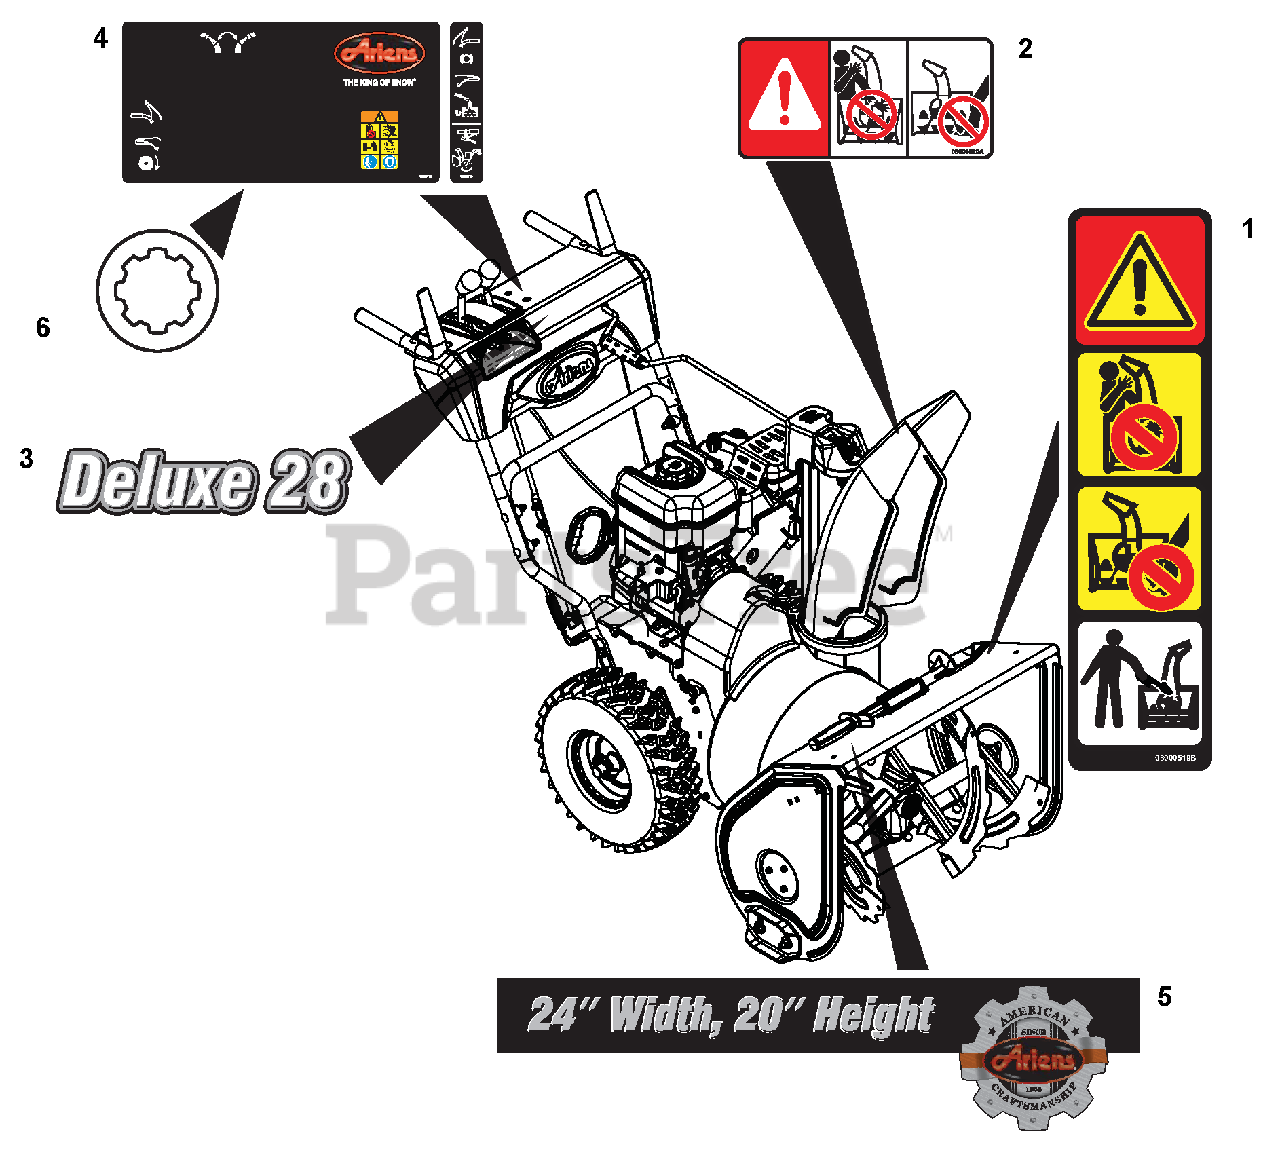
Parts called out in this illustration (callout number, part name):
1	DECAL, DANGER - ROTATING PARTS
2	DECAL, DANGER
3	DECAL, DELUXE 28 SM DASH
4	DECAL, CONTROL - DLX PIN-LOCK
6	DECAL,AUTODIFFERENTIAL
